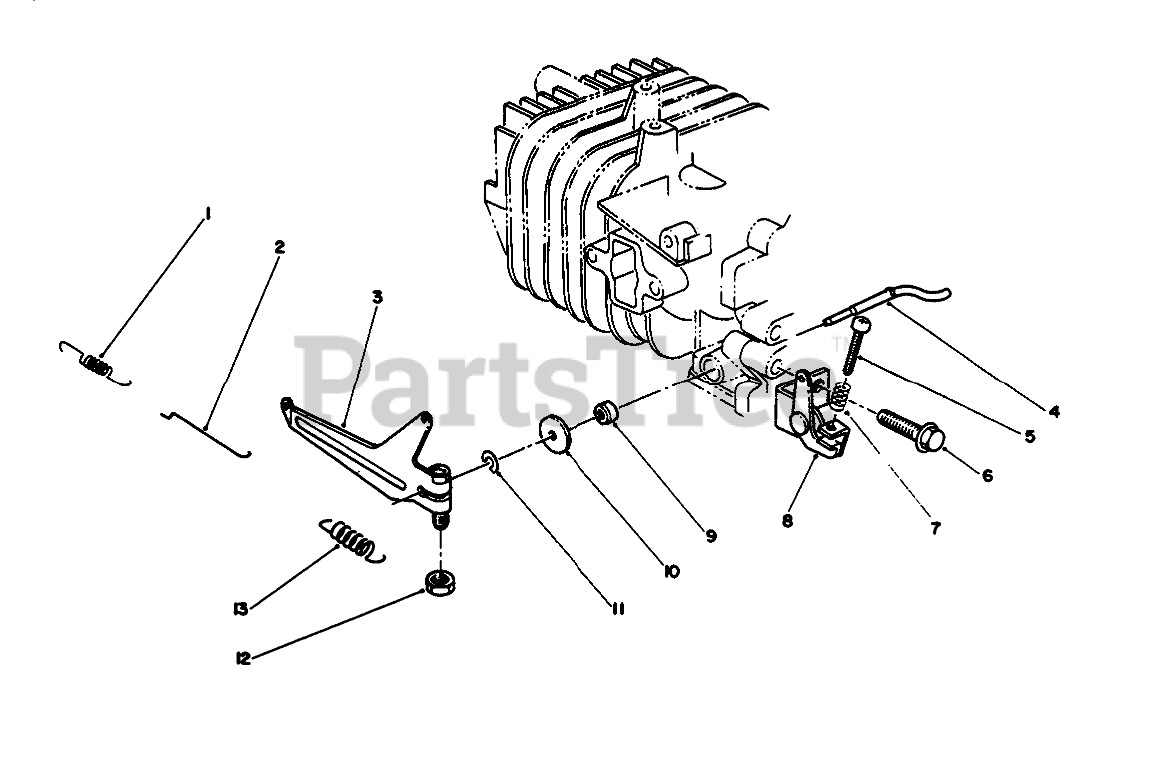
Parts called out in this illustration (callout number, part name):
1	CARB SPRING
2	CARB ROD
3	GOVERNOR ARM
4	SHAFT
5	SCREW
7	SPRING
8	GOV SPR BRKT
9	SEAL-OIL
10	WASHER
11	E-RING
13	GOV SPRING
